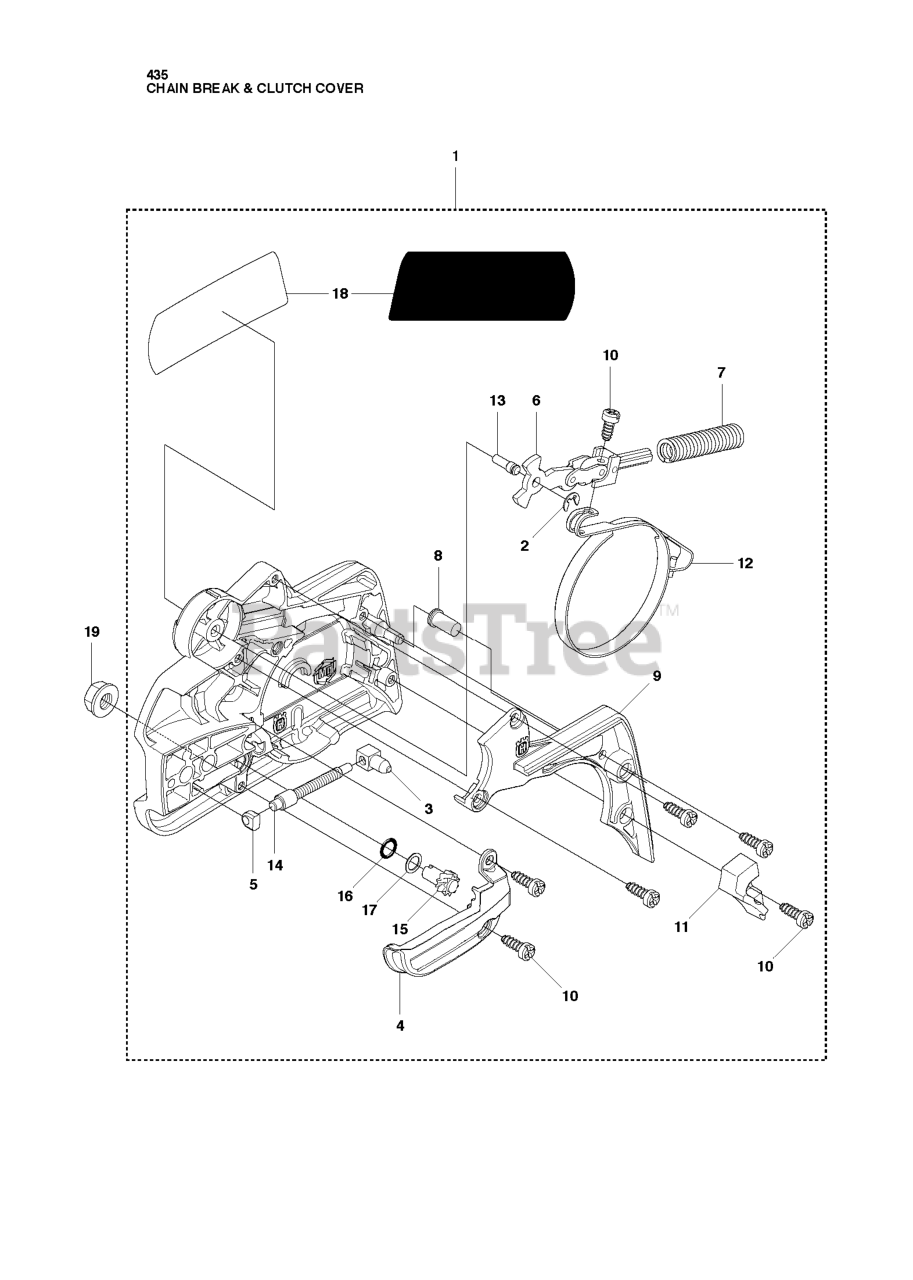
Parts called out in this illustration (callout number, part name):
1	CLUTCH COVER ASSY
4	CHAIN GUIDE
7	BRAKE SPRING
11	WEAR PROTECTION
12	BRAKE BAND ASSY
15	WORM WHEEL
18	LABEL 400 SERIES
19	NUT M8 FLANGE
